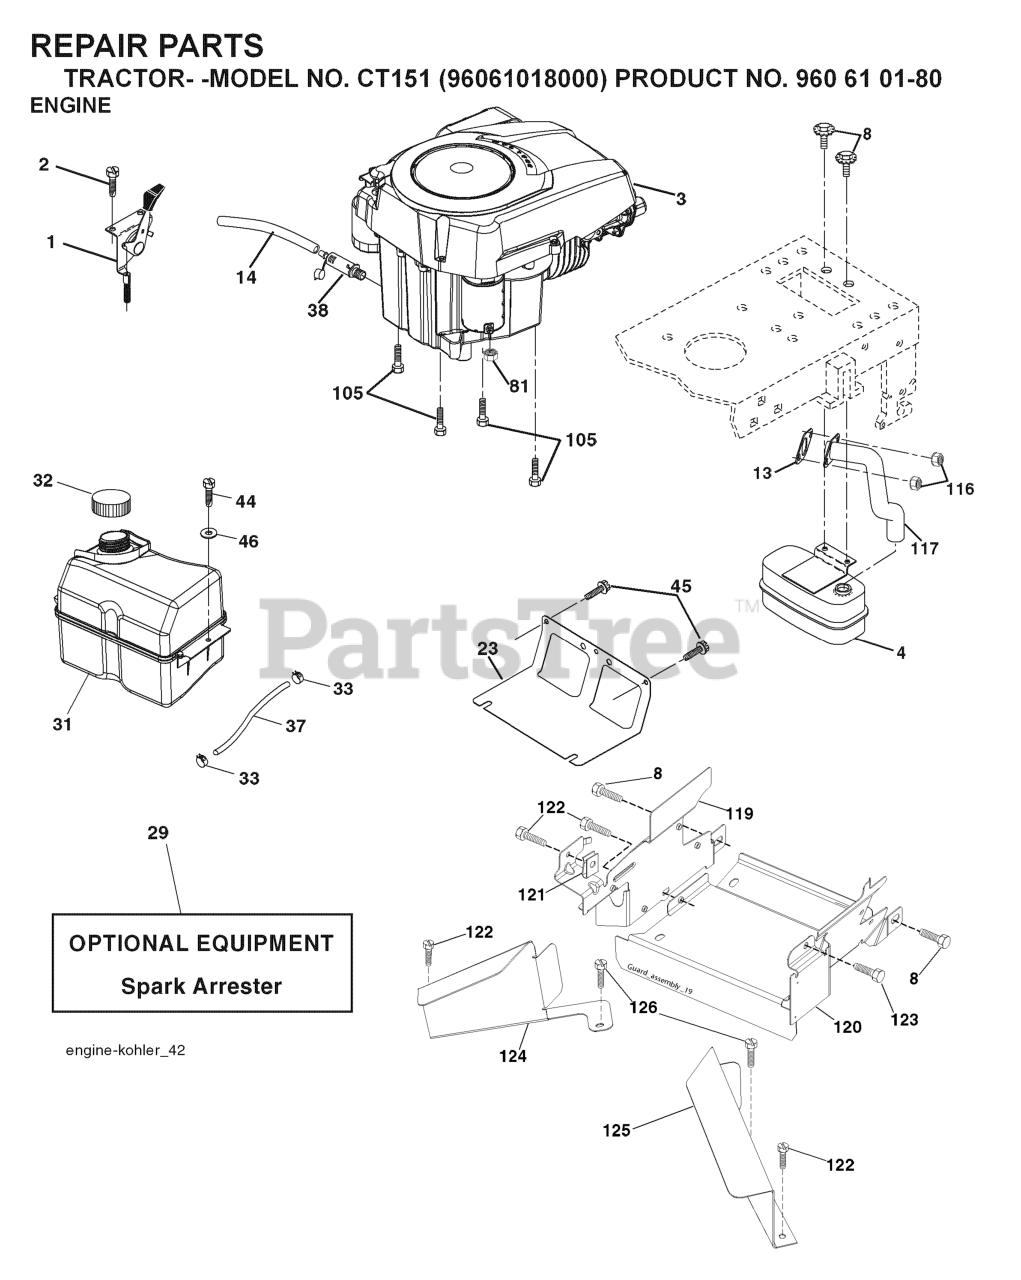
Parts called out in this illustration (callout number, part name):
1	COMFORT STEERING
5	SCREW MC6S 6X20
7	BALL BEARING 6004-2RS1
9	RETAINING RING SGA 20
12	RETAINING RING
14	COLLAR SCREW
15	BALL BEARING 6010 2RS1
16	Ball Bearing 6005-2rs
17	CIRCLIP SGH 47
20	Retaining Ring
21	RETAINING RING SGA 25
22	NUT
23	NUT
27	NUT
28	PROTECTIVE COVER
30	NUT FLANGE
39	DRIVER STEERING WHEEL
40	STEERING WHEEL
